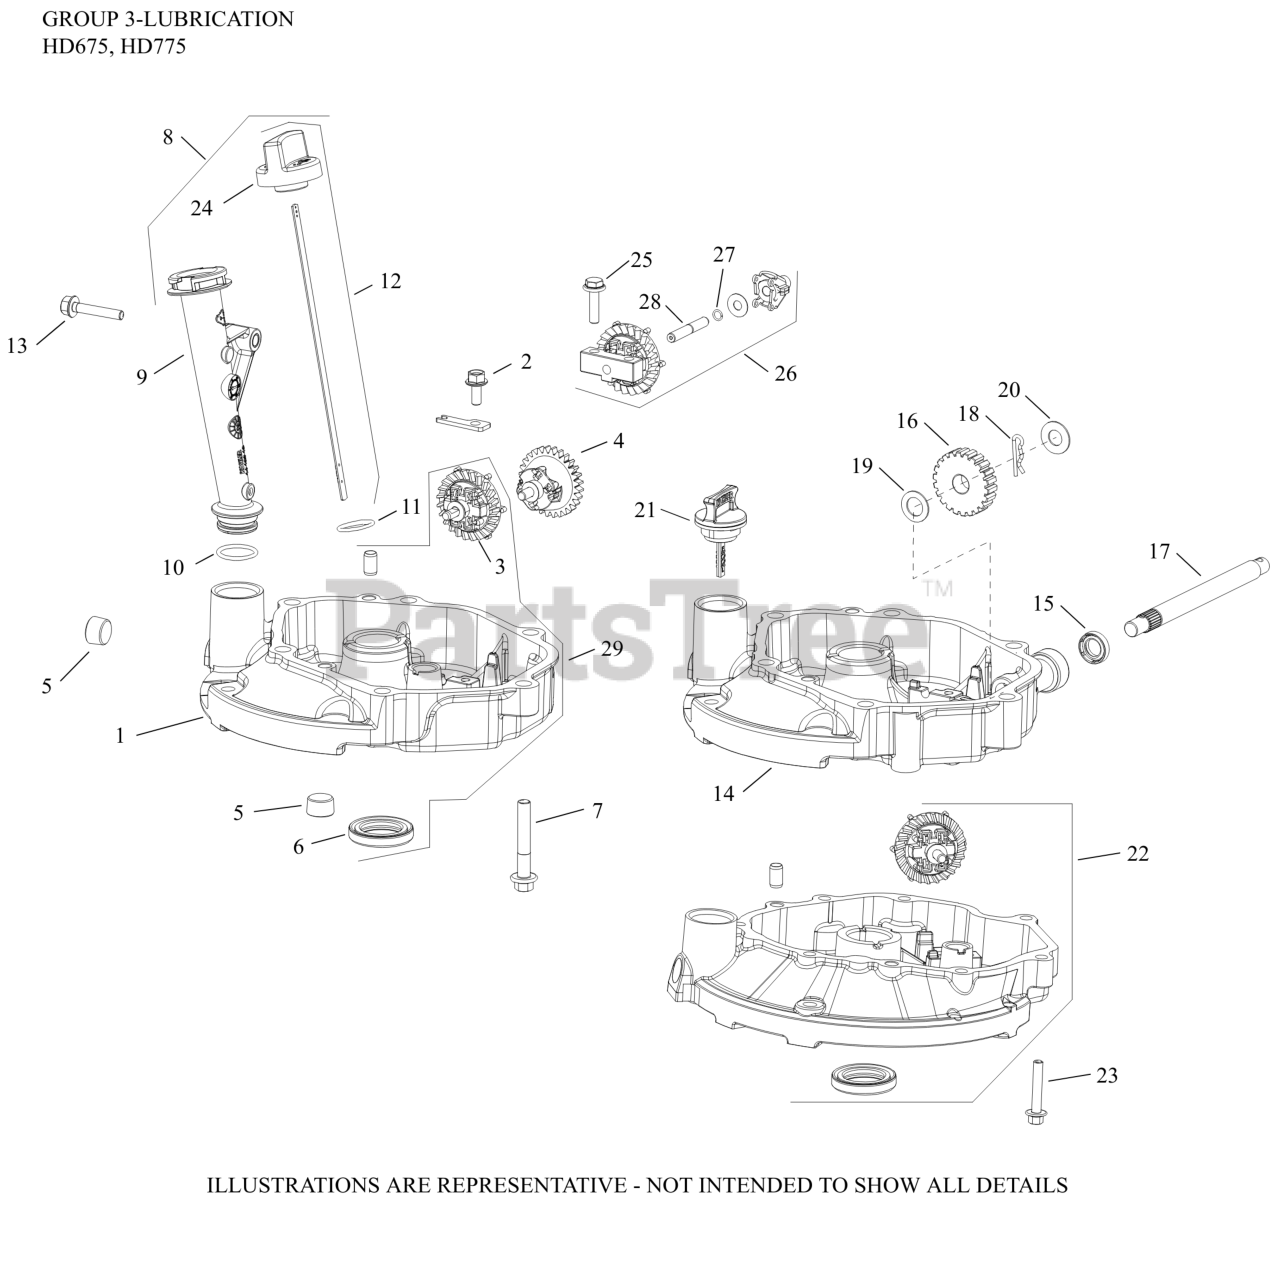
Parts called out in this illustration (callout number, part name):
5	PLUG, PIPE (W/SEALANT)
7	SCREW, HEX FLANGE (M8)-USE 25 086 456-S
8	KIT, DIPSTICK AND TUBE-(#1412320S)
9	TUBE ASSEMBLY, OIL FILL
10	O-RING, OIL FILL TUBE
11	O-RING (CAP)
12	CAP, DIPSTICK ASSEMBLY
13	SCREW, HEX FLANGE (M6)-(#25086435S)
25	SCREW, M6 X 22
26	GOVERNOR GEAR, ASSEMBLY
27	CLIP, GOVERNOR GEAR-DISCONTINUED
28	SHAFT, GOVERNOR GEAR-DISCONTINUED
